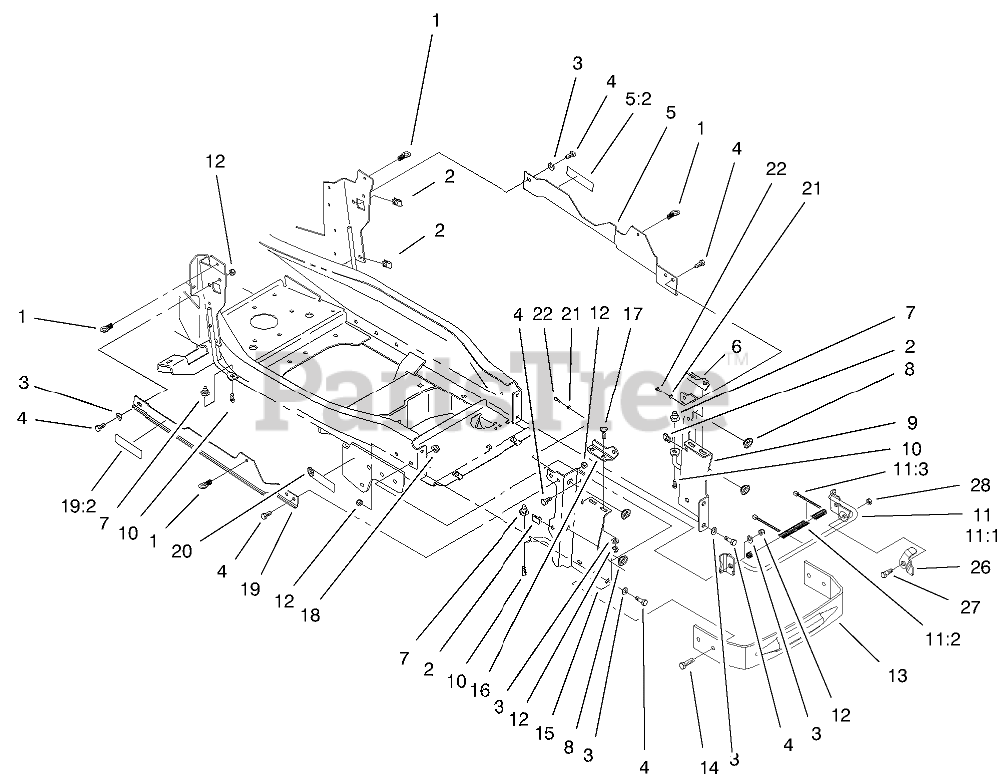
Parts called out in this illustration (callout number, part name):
1	LATCH ASM
3	WASHER-PLAIN
4	SCREW-HH
5	ASM-Support w/Decal (Only On: 73547)
5	ASM-Support w/Decal (Only On: 73580)
5:2	Decal-Warning (Only On: 73547)
5:2	Decal-Warning (Only On: 73580)
6	BRACKET-HINGE, LOWER LH
7	MOUNT-SIDEPANEL
8	GROMMET
9	SUPPORT-HOOD, LH
10	SCREW-PLASTITE
11	SUPPORT-HOOD
11:1	Hood Support Brace W.a.
11:2	COVER-BRACE
11:3	TIE-CABLE
12	NUT-LOCK, NI
13	BUMPER-FRAME
14	SCREW-HH
15	SUPPORT-HOOD, RH
16	BRACKET-HINGE, LOWER RH
17	SCREW-CARR
18	NUT-LOCK, NI
19	ASM Support/Decal (Only On: 73580)
19	ASM-Support/Decal (Only On: 73547)
19:2	Decal-Warning (Only On: 73547)
19:2	Decal-Warning (Only On: 73580)
20	DECAL-ATTACH A-MATIC
21	Washer-Flat (Only On: 73580)
22	Screw-Selftap (Only On: 73580)
26	LEVER-PROP, HOOD
27	BOLT-SHOULDER
28	NUT-LOCK, NI
